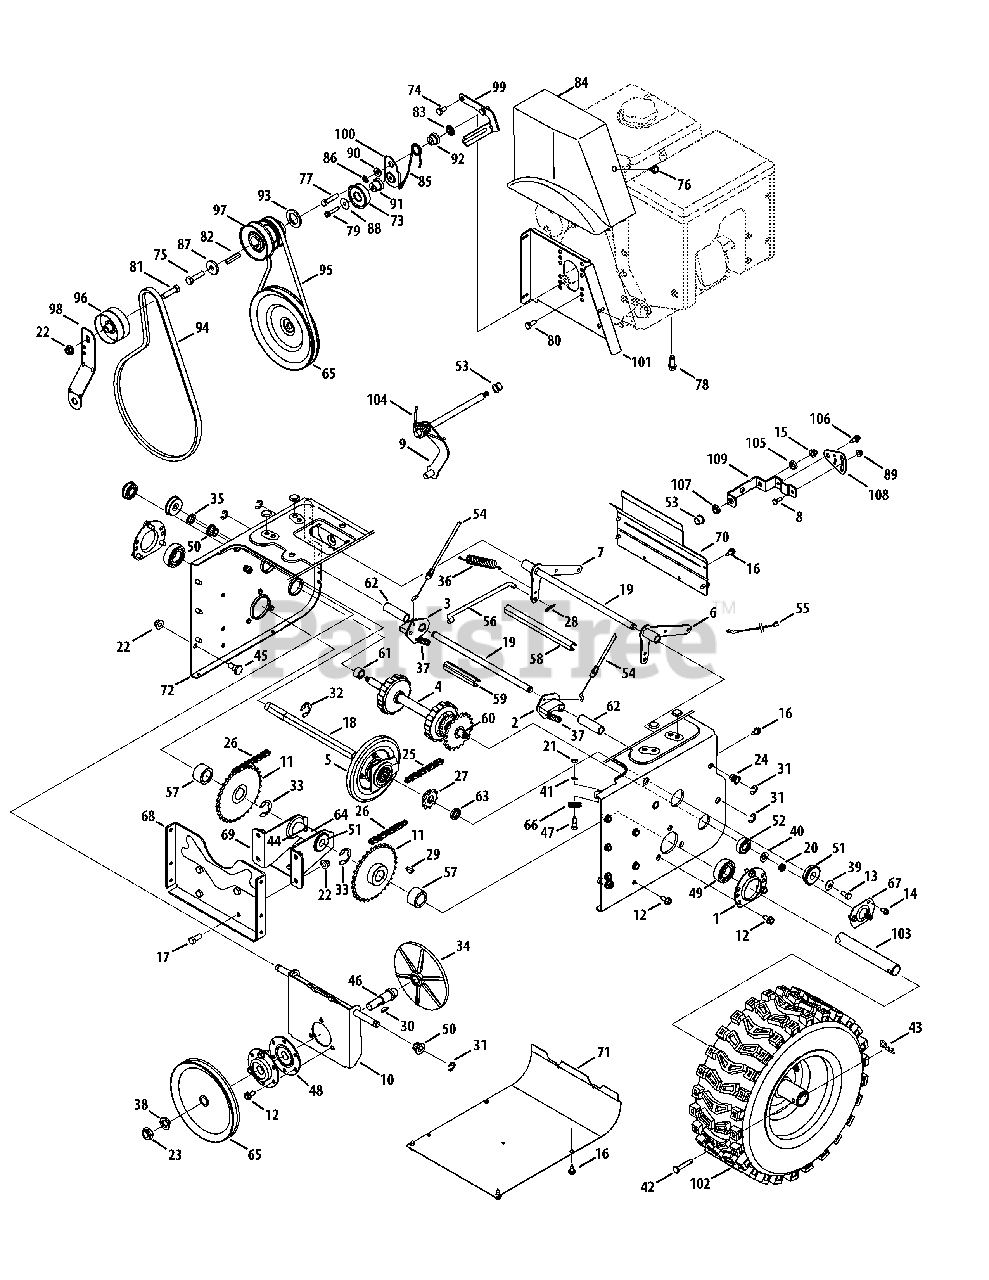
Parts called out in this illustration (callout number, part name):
1	Housing, Bearing
2	Dogg, Steering Drive, LH
3	Dogg, Steering Drive, RH
4	Shaft Assembly, Steering
5	Assembly, Friction Wheel
5	Wheel, Friction, Bonded
5	Screw, Hex Wash
6	Bracket, Auger Actuator
7	Bracket, Drive Actuator
8	Hex Head Screw, 1/4-20
9	Rod Assembly, Shift
10	Brkt, Friction Drive Suprt.
11	Sprocket, 32T
12	TT Screw, 5/16-18 x .750
13	Screw, Hex Cap Lock,
14	Screw, Hex, 1/4-20 x .50
15	Flange Lock Nut 5/16-18
16	Screw, Hex Wash.
17	Screw, Hex Cap, 3/8-16
18	Shaft, Hex Drive
19	Shaft, Actuator
20	Nut, Hex Insert Jam Lock
21	Nut, Hex, 1/4-28 GR5
22	Nut, Hx Flnge Insert Lk
23	Nut, Hx Insert Jam Lk
24	Nut, Insert 3/8-16
25	Chain, Endless, #41 x 36L
26	Chain, #420 x 40L
27	Sprocket, #41 x 10T
28	Pin, Internal Cotter
29	Key, Woodruff
30	Key, Hi-Pro, 3/16 x 5/8
32	Ring, Retaining
33	Ring, Retainer
34	Plate, Drive
35	Speed Nut, .500
36	Spring, Extension
37	Spring, Extension
38	Washer, Lock, 5/8
39	Wsh, Bell., .34 x .872 x .06
40	Wash, .375 x .812 x .060
41	Washer, Lock, 1/4
42	Pin, Clevis
43	Pin, Internal Cotter
44	Fitting, Lube, 3/16 Drive
45	Screw, Shldr., .498 x .34
46	Spindle, Drive Plate
47	Screw, Hex Shldr., 1/4-28
48	Ass’y, Bearing/Housing
49	Bearing, Self Aligning
50	Bearing, Hex Flange
51	Bearing, Ball
52	Bush, Flg, .5625 ID x 1.375 x .4375
53	Bush, Flg, .5 ID x .627 OD
54	Cable, Steering
55	Cable, Auger Idler
56	Rod, Drive Clutch
57	Spacer, 1.01 x 1.50 x .93
58	Spacer, .49 x 7.865
59	Spacer, .49 x 3.545
60	Spacer, .566 x .87 x .190
61	Spacer, .566 x .87 x 1.25
62	Spcr., .514 x .632 x 2.44
63	Spacer, .675 x 1.0 x .23
64	Spcr, .6725 x 1.125 x 2.48
65	Pulley, Drive
66	Roller, Cable
67	Retainer Bracket
68	Bracket, Frame Support
69	Bracket, Axle Support
70	Cover, Upper Frame
71	Cover, Lower Frame
72	Trans Frame
73	Idler Pulley Assembly
74	Screw, Hex 5/16-24 x .75
75	Screw, Hex 3/8-24 x 1.25
76	Screw, Hx Wash Hd Tapp
77	Screw, Hex Cap, 5/16-24 x 1.50
78	Screw, 3/8-16 x 1.00
79	Screw, 1/4-20 x 1.25
80	Screw, Shldr., .500 x .145
81	Screw, Hex Cap, 3/8-16 x 1.75
82	Key, Square, 1/4 x 1.5
83	Nut, Push
84	Cover, Belt
85	Torsion Spring, .850 dia. x .333 lg.
86	Washer, Lock, 5/16
87	Washer, Flat, .406 x 1.25
88	Washer, Flat, .265 x 1.0 x .030
89	Flange Lock Nut 1/4-20
90	Shldr. Spacer, .3175 x .500 x .094
91	Shldr. Spacer, .260 x .785 x .538
92	Shoulder Spacer, .340 x 1.00
93	Spacer, 1.02 x 1.63 x .1425
94	V-Belt, 4L x 44.60
95	V Belt, 3/8 x 36.68
96	Pulley, Flat Idler, 2.75 OD
97	Double Pulley, 3.25 x 2.75
98	Bracket, Auger Idler
99	Belt Keeper Bracket
100	Idler Drive Wheel Bracket
101	Belt Cover Bracket
102	Wheel Ass’y. - LH
102	Wheel Ass’y. - RH
103	Axle, Wheel, 45"
104	Torsion Spring, .750 I.D. x .968 Lg.
105	Flat Washer, .469 x .875 x .105
106	Shoulder Screw, .368 x .113
107	Spacer, .515 ID x .750 OD x .220
108	Speed Selector Pivot Bracket
109	Speed Selector Shift Bracket
